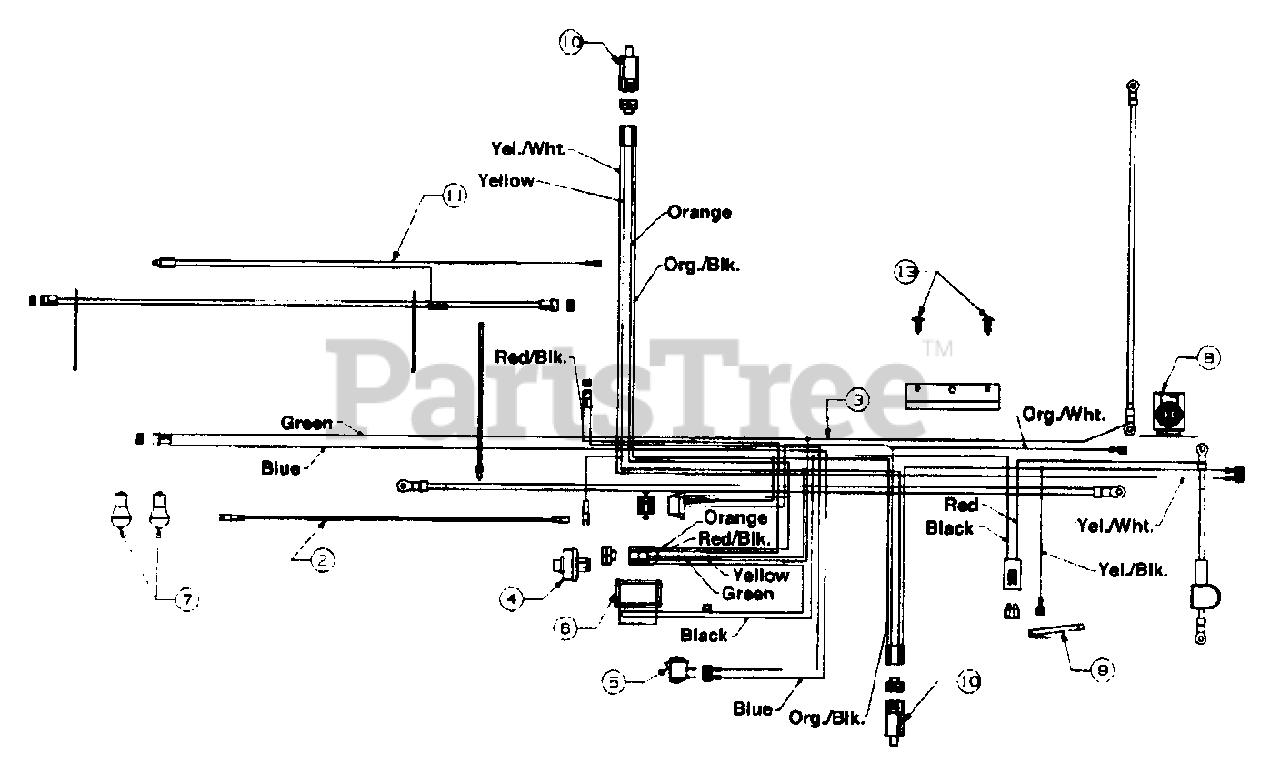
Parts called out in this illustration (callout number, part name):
2	Harness Adapter
3	Wire Harness w/Light Switch & Amp
4	Ignition Switch
5	Light Switch
6	Ammeter
7	Bulb
8	Solenoid
9	Safety Switch (Reverse)
10	Safety Switch
11	Harness Adapter (Alt.)
13	Ratchet
